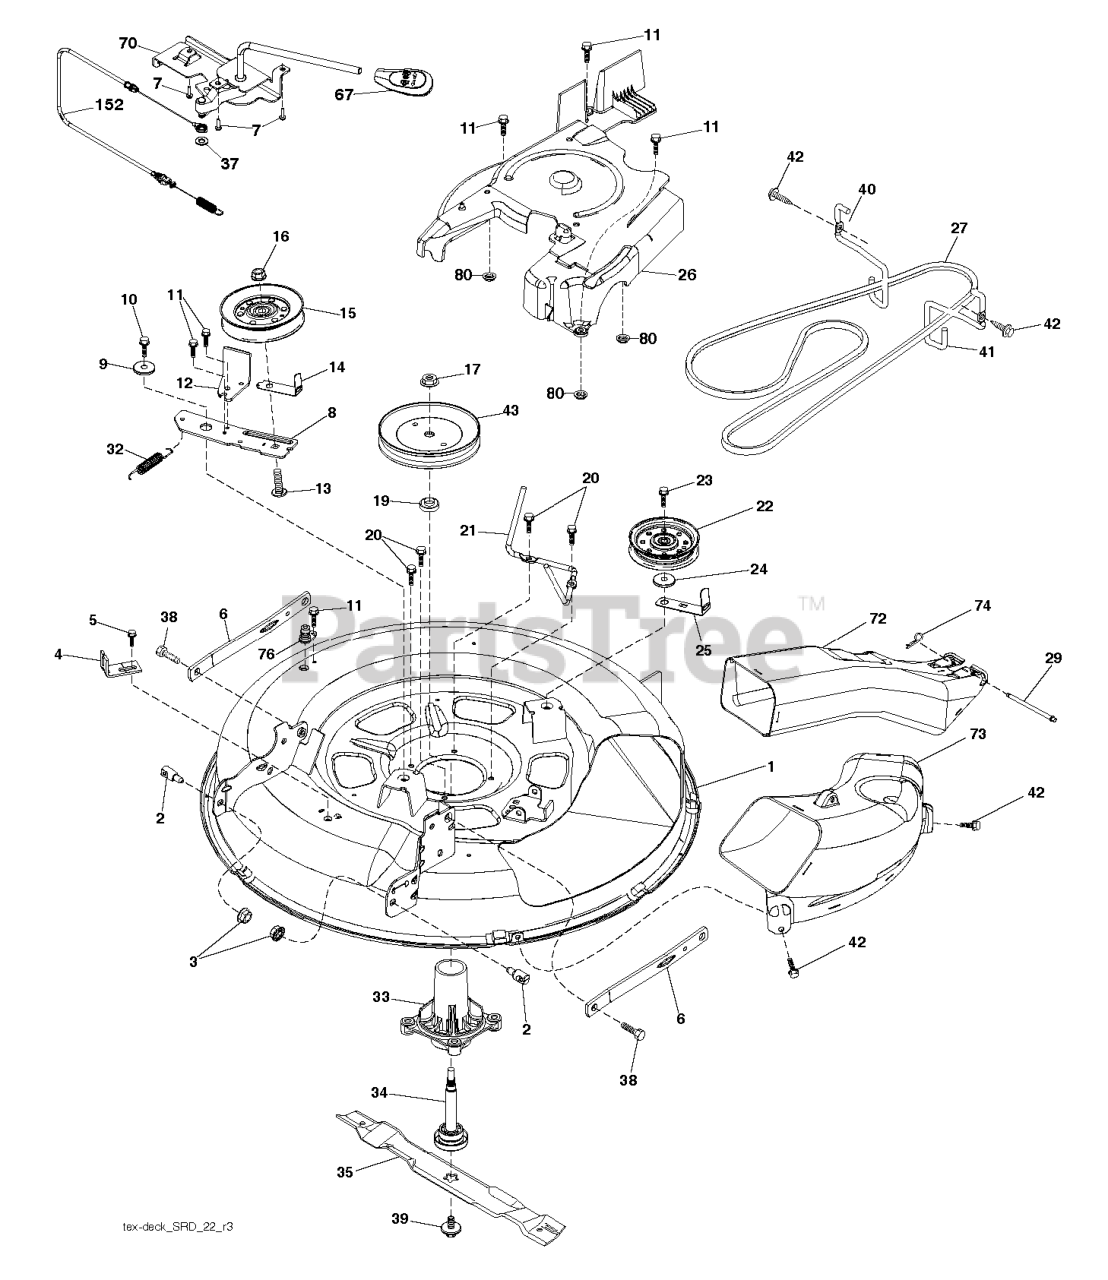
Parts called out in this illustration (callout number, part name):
1	DECK.WELDMENT.PNT.30"SRD
2	STUD.FASTNER.W/ANTI-ROTATE
3	NUT LOCK HEX FLANGE 5/16-18
4	BRACKET.CLUTCH.CABLE
5	BOLT.5/16HEX.WHS.HD
6	ARMS.SUSP.MOWER.REAR.SRD
7	SCREW.#10 X 0.750.BOS
8	ARM.IDLER.30"SRD
9	SPACER.RETAINER
10	SCREW 3/8-16X1
11	SCREW.1/4-20X5/8
12	RP ARM.BRAKE.MOWER.38"LH.TEX
13	BOLT.3/8-16X1.50
14	KEEPER, BELT IDLER
15	PULLEY.IDLER.4.25
16	NUT LOCK FLG 3/8-16 UNC
17	NUT.FLANGE.LOCK.TOP
18	WASHER.SPACER.MANDREL
20	SCREW, WASHER HEAD
21	KEEPER.BELT.MANDREL.30"
22	PULLEY.IDLER.FLAT.46.PR.DR.
23	SCREW LT
24	WASHER
25	KEEPER.BELT.30"SRD
26	COVER.ASM.MANDREL.30"
27	V-BELT.DRIVE.MOWER.30"
29	PIN.HINGE.30".SRD
32	SPRING RETURN
33	RP.HOUSING.MANDREL.4PT.
34	SHAFT.ASM.MDRL.N/GREASE.38
35	BLADE.MOWER.BAGGING.30"
36	BOLT.WASHER.ASM.7/16-2
37	WASHER
38	BOLT.SHOULDER
40	KEEPER.BELT.ENGINE.LH.LT.SRD
41	KEEPER.BELT.ENGINE.RH.LT.SRD
42	SCREW, 3/8-16X3/4
43	PULLEY, MANDREL 6.5 PD
67	HANDLE.CLUTCH.CABLE.LT
70	CLUTCH.ASM.MANUAL.LT.PRED
72	CHUTE.UPPER.SRD.30R"
73	CHUTE.LOWER.SRD.30R"
74	RETAINER-SPRNG RB
76	PORT.WASHOUT
80	PALNUT 1/4
152	CABLE.CLUTCH.MANUAL.
